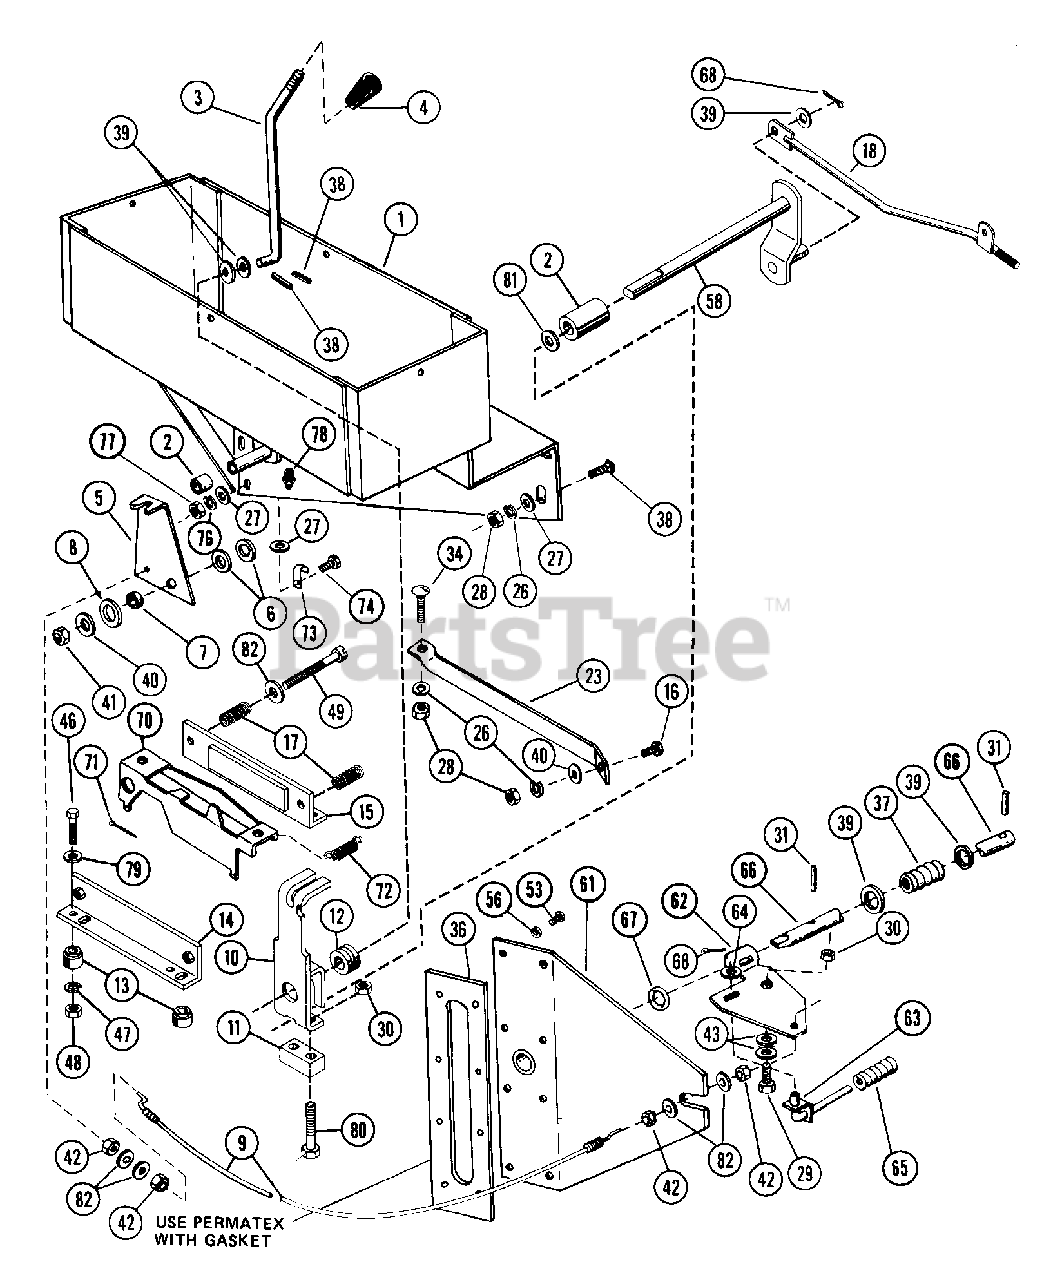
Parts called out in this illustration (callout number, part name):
1	CONTROL BOX
2	BSHG-SLV .625X.750X1.000
3	SHIFT ROD
4	HANDLE
6	WSHR-FL-STL .438X1.125X.19
7	BSHG-SLV .377X.624X.235
8	BELLEVILLE WASHER
12	GROMMET .438ID X .688 OD
13	SPACER .344X.750X.625X.500
14	R.H. FRICTION BRAKE
15	L. H. FRICTION BRAKE
16	BLT-HEX .38-16X.75 PL GR2
17	SG-COMP .093X.59X1.50
18	SHIFT ROD
26	WSHR-LK .375X.094 MED PL
27	WSHR-FL-STL .438X1.0X.083 PL
28	NUT-HEX .375-16
29	BLT-HEX .31-18X.75 PL GR5
30	NUT-LK-TOP .312-18 GR C PL
31	PIN-ROLL .188X1.25
34	BLT-RDHDSQSHNK .38-16X1.00 PL
37	SG-COMP .072X.687X.75
38	PIN-ROLL .188X.88
39	WSHR-FL-STL .531X1.062X.095 PL
40	WSHR-FL-STL.406X.812X.065PL
41	NUT-LK-CTR .375-16 GR A PL
42	NUT-JAM .312-24 PL
43	WSHR-FL-STL.344X.688X.065PL
44	BLT-RDHDSQNK .38-16X1.0 PL
45	BLT-HEX .38-16X2.50 PL GR5
46	BLT-HEX .31-18X1.25 PL GR2
47	WSHR-LK .312X.097 PL HVY
48	NUT-HEX .312-18
49	SCR-MCH .31-18X2.75 SLRH PL
53	SCR-TAP 12-24X.50 HWH PL TR
56	WSHR-LK-EXT 12X.025 PL
58	SHIFT SHAFT
61	LOCK PIN GUIDE
62	LOCK PIVOT PLATE
63	PIVOT PIN
64	WSHR-FL-STL .344X1.375X.075 PL
65	SG-COMP .092X.77X3.13 WLD 36
66	LOCK PIN
67	O-RING .500X.629X.070
68	PIN-COTR .12X1.0 PL
70	SHIFT LOCK
71	PIN COTR .09X.50 PL
72	SG-TENS .035X.45X2.75 WLD 3.5
74	BLT-HEX .38-16X1.00 PL
76	WSHR-LK .375X.094 MED PL
77	NUT-HEX .375-16
78	ZERK FITTING
79	WSHR-FL-STL .323X.625X.062 PL
80	BLT-HEX .31-18X1.50 PL GR5
81	WSHR-FL-STL .630X1.005X.062 PL
82	WSHR-FL-STL .323X.625X.062 PL
